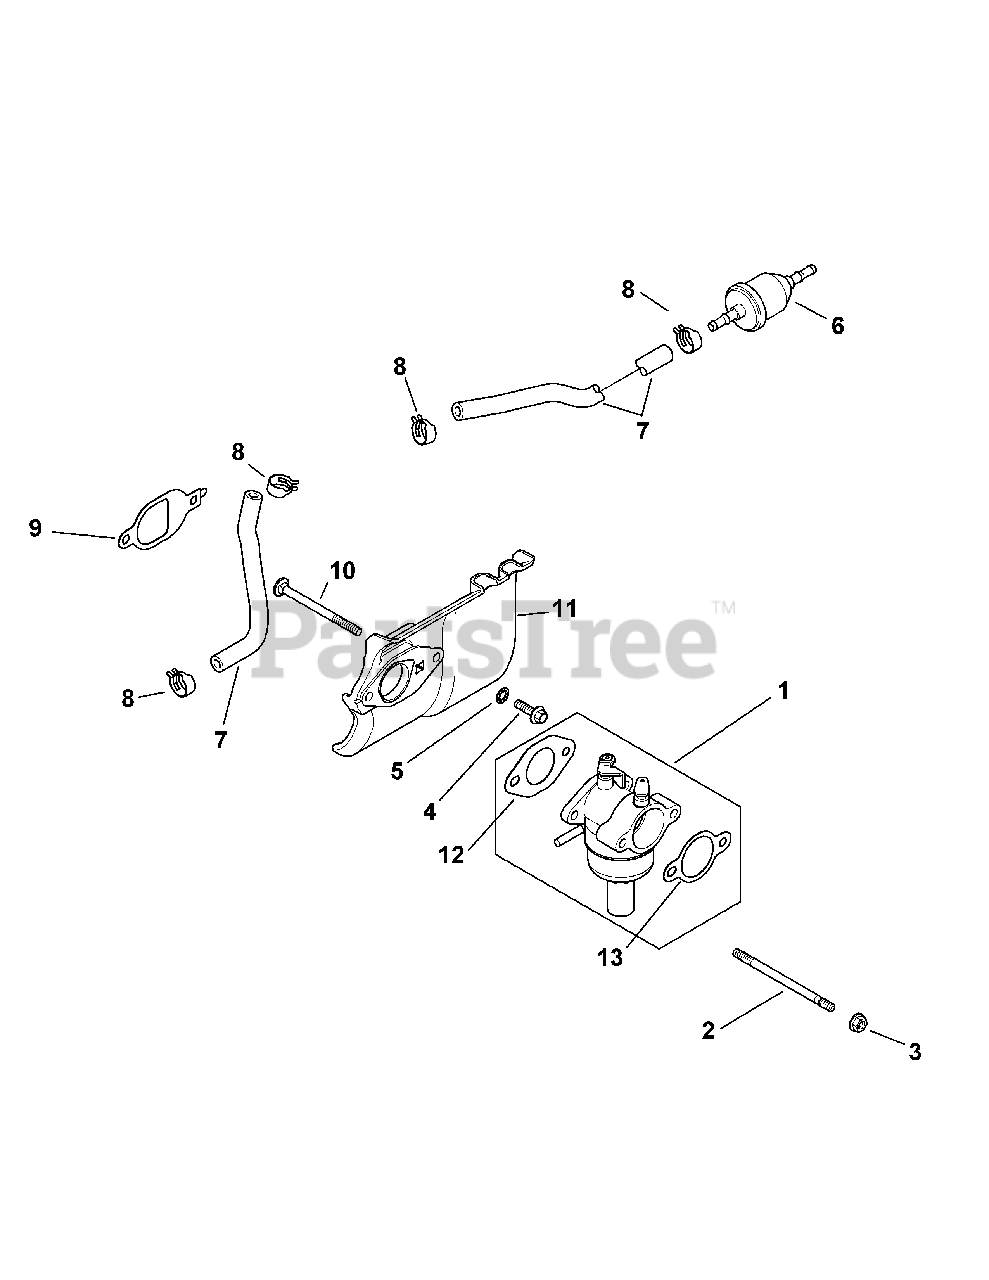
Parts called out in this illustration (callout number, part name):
1	Carburetor Kit (Inc. 12 & 13)
2	Stud, M6 X 1.0 X 100
3	Flange Nut, M6 X 1.0
4	Flange Screw, M6 X 1.0 X 20
5	Int. Tooth Lock Washer, 1/4
8	Hose Clamp, 1/2
9	Heat Deflector Gasket
10	Carburetor Stud
11	Heat Deflector Kit
12	Carburetor Gasket
13	Air Cleaner Base Gasket
